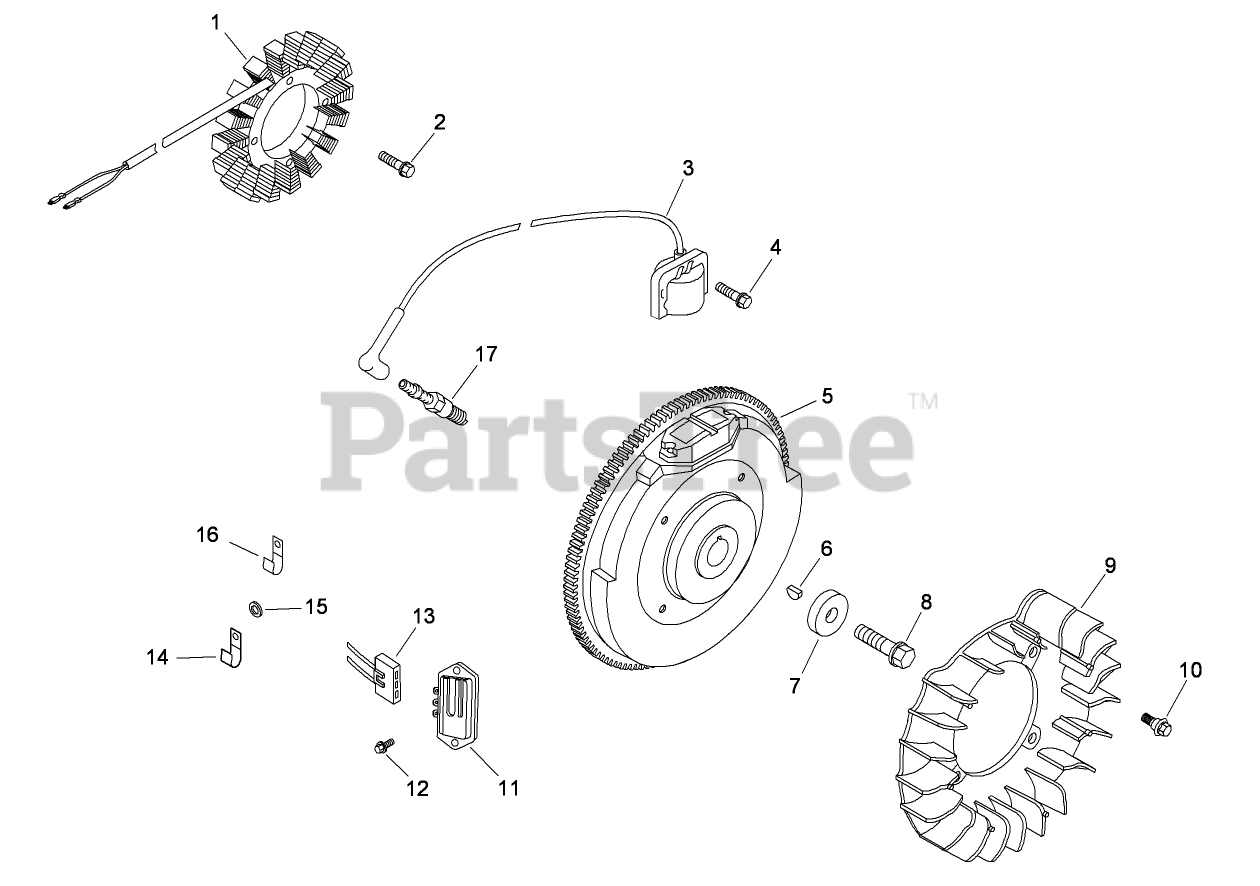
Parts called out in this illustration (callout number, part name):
1	Stator Kit (15 AMP) (IncludesTerminal)
2	SCREW-THREAD FORMING (M5X0.8X25)
3	MODULE-IGNITION (C D I FIXED)
4	SCREW-FLANGE, THREAD FORMING (M5X.8X20)
5	Flywheel ASM
6	KEY (3/16 X 5/8)
7	WASHER-FLAT (13/32)
8	SCREW-FLANGE (M10X1.5X45)
9	Fan
10	BOLT-SHOULDER (M6x1.0x16)
11	Rectifier-Regulator
12	SCREW-HEX FLANGE, HI-LO
13	Connector (3 contact)
14	CLIP-CABLE
15	WASHER-FLAT (1/4)
16	Clip
17	SPARK PLUG (PRO SERIES)
